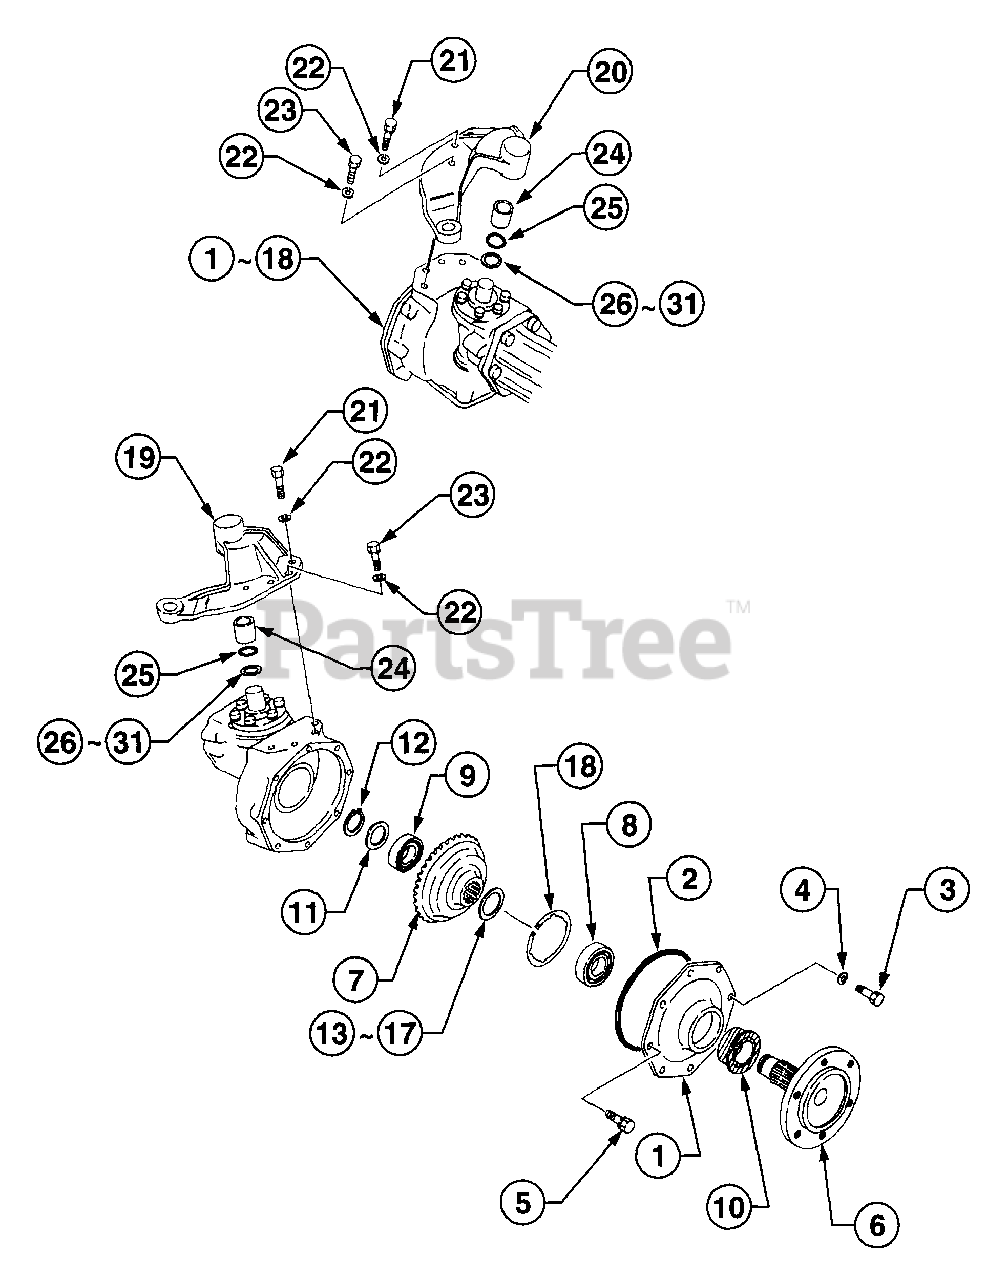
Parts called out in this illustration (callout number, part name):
4	Washer, Spring
5	Bolt, w/Washer
8	Bearing, Ball
9	Bearing, Ball
13	Liner, t=0.15
19	Arm L.H., Knuckle
20	Arm R.H., Knuckle
22	Washer, Spring
23	Bolt w/Washer
26	Liner A, t=1.0
27	Liner B, t=1.2
28	Liner C, t=1.4
29	Liner D, t=1.6
30	Liner E, t=1.8
31	Liner F, t=2.0
